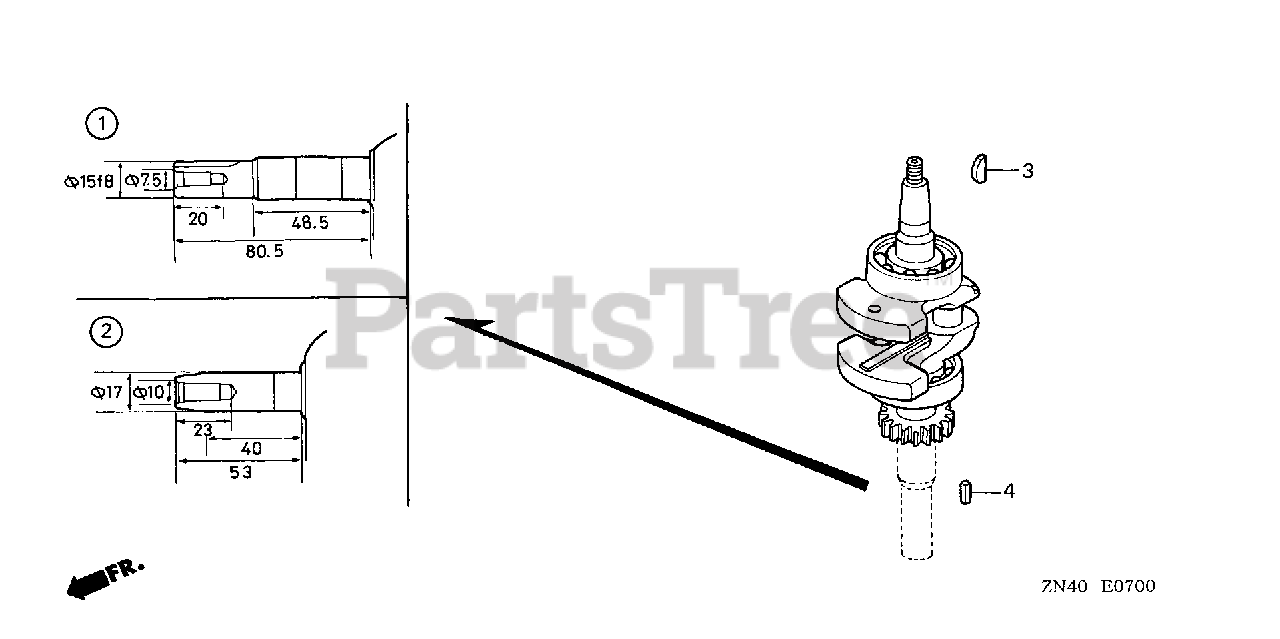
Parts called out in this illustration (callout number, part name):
1	CRANKSHAFT
3	KEY, SPECIAL
4	KEY (5MM)
